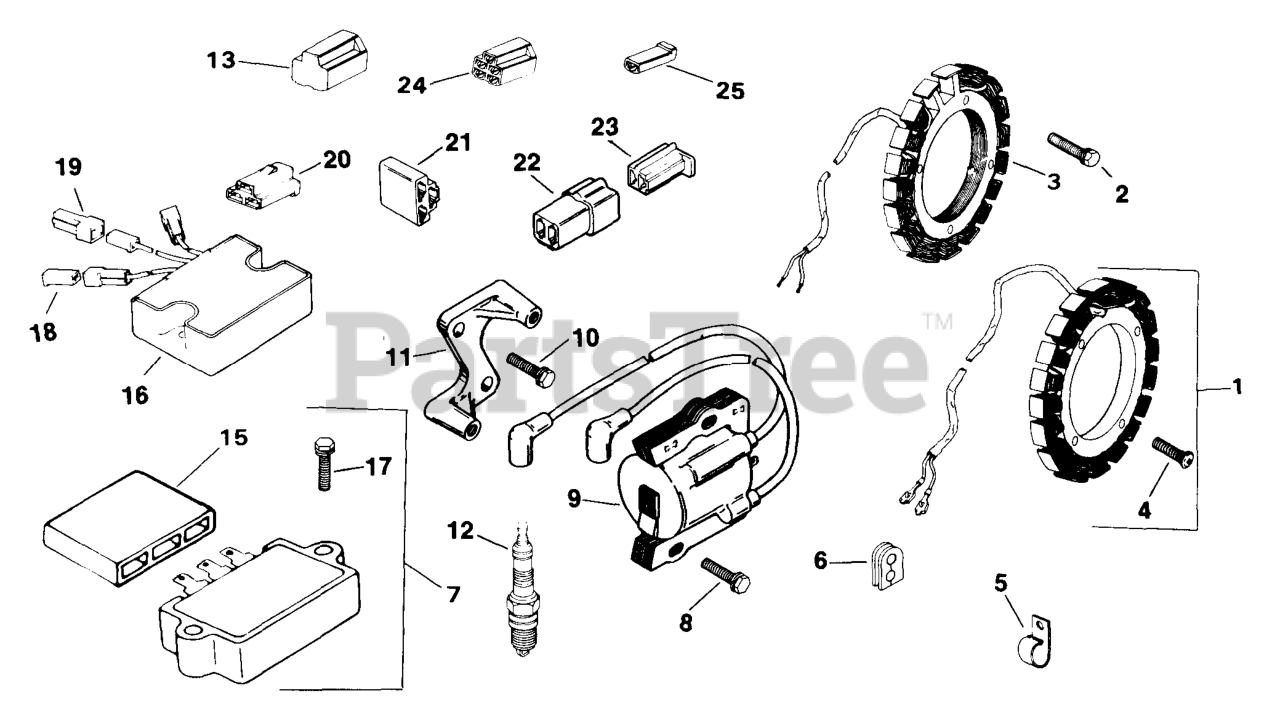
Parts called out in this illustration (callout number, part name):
1	Kit, Stator (15 Amp)
2	Screw, Hex. Wash. Hd. 10-24x3/4"
7	Kit, Rectifier-Regulator, 15 Amp
8	Screw, Hex. Wash. Hd. 1/4-20x1"
10	Screw, Hex. Wash. Hd. 1/4-20x1"
11	Bracket, Module
12	Spark Plug (Rv15yc)
15	Connector, Female (3 Contact)
17	Screw, H.C. Sems 1/4-20x5/8"
21	Connector, Female (3 Contact)
